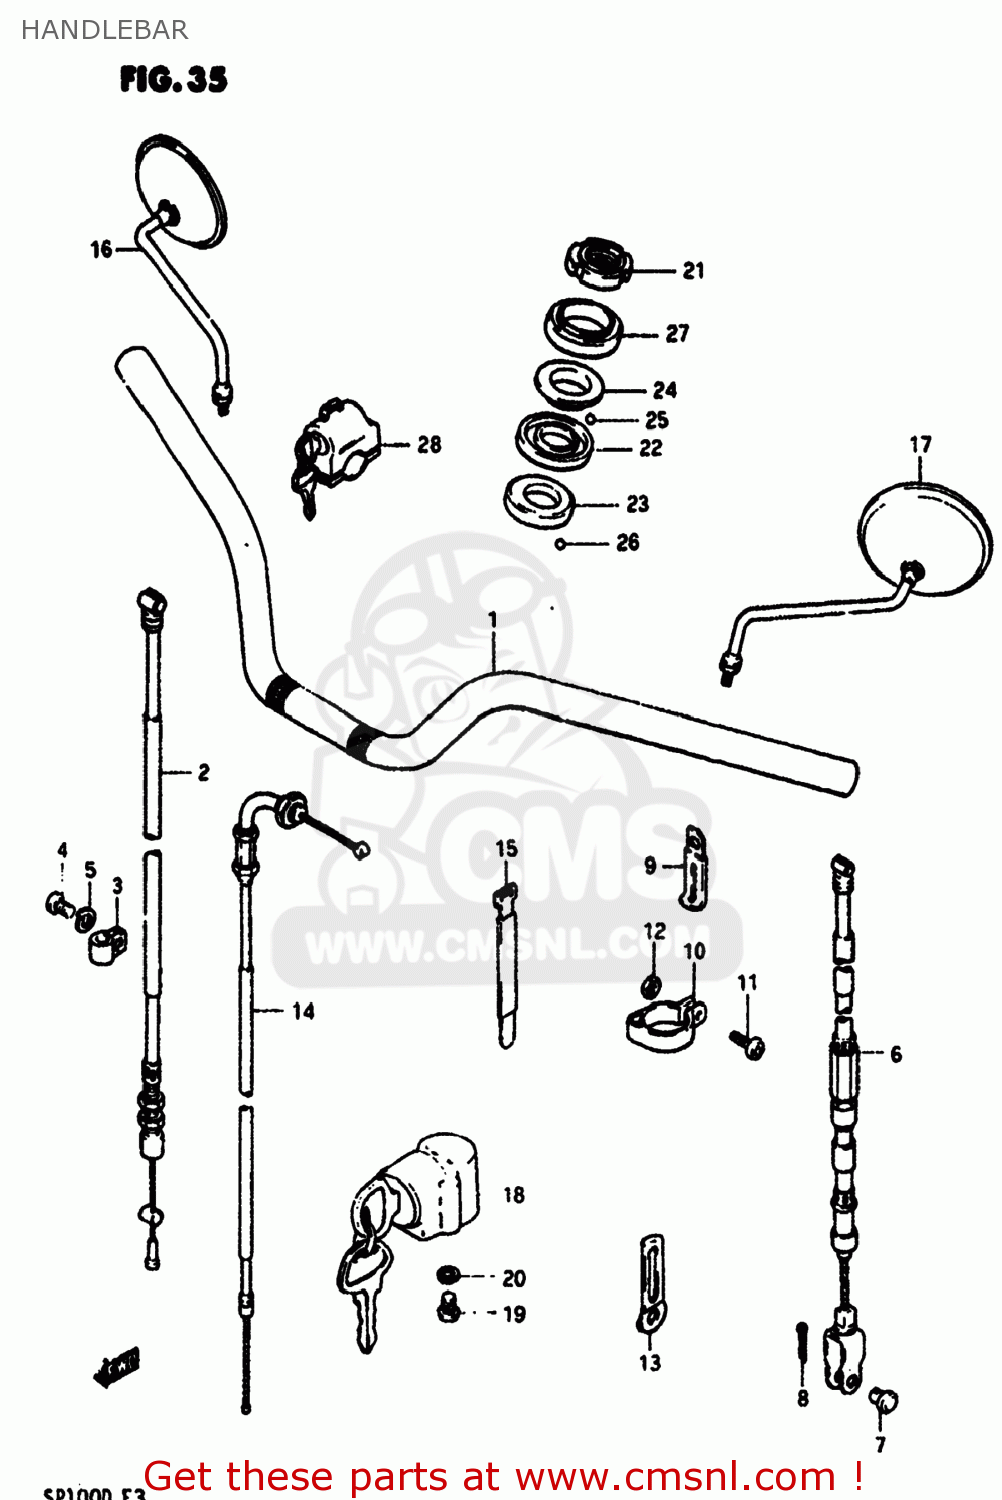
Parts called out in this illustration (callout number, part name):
1	HANDLEBAR
2	CABLE,FRONT BRAKE
3	GUIDE,CABLE
4	SCREW
5	LOCK WASHER
6	CABLE ASSY,CLUTCH
7	PIN(L:15)
8	PIN
9	CLAMP
10	CLAMP,CABLE
11	SCREW
12	NUT
13	CLAMP,CABLE
14	CABLE ASSY,THROTTLE
15	CLAMP
16	MIRROR ASSEMBLY,RIGHT
17	MIRROR ASSEMBLY,LEFT
18	LOCK ASSY,STEERING
19	SCREW
20	LOCK WASHER
21	NUT,STEERING STEM(25X44X10)
22	RACE,STEERING INNER UPR
23	LACE,STEERING INNER LWR
24	RACE,STEERING OUTER UPR
25	BALL
26	BALL
27	DUST SEAL,STEERING UPR
28	LOCK ASSY,HELMET
